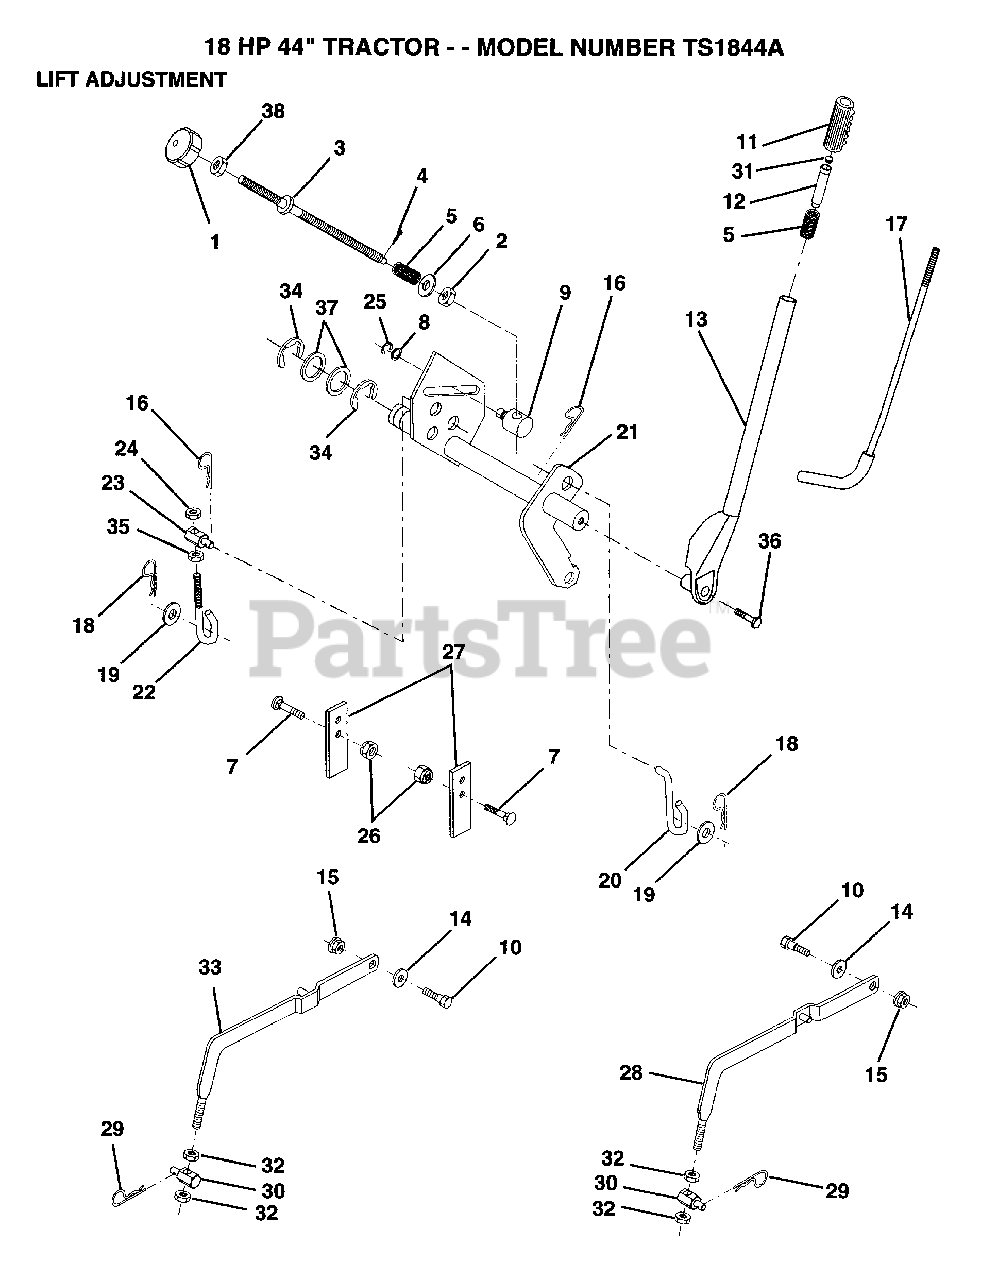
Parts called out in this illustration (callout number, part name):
1	KNOB INF 3/8-16
2	NUT T
3	ROD LIFT LT
5	SPRING T
6	WASHER
8	WASHER
9	TRUNION LT
10	"BOLT, SHOULDER LT"
11	GRIP
14	WASHER T
15	NUT SPECIAL T
17	LEVER ROD LT
18	SPRING.RETAINER
20	LIFT LINK LT
22	PIVOT PIN T
25	KLIP RING
27	UPSTOP
28	RH SUSP ARM ASM
29	SPRING H
32	NUT
33	LH SUSP ARM ASM
34	E-RING
35	NUT
36	"BOLT,HEX"
37	WASHER
38	NUT
